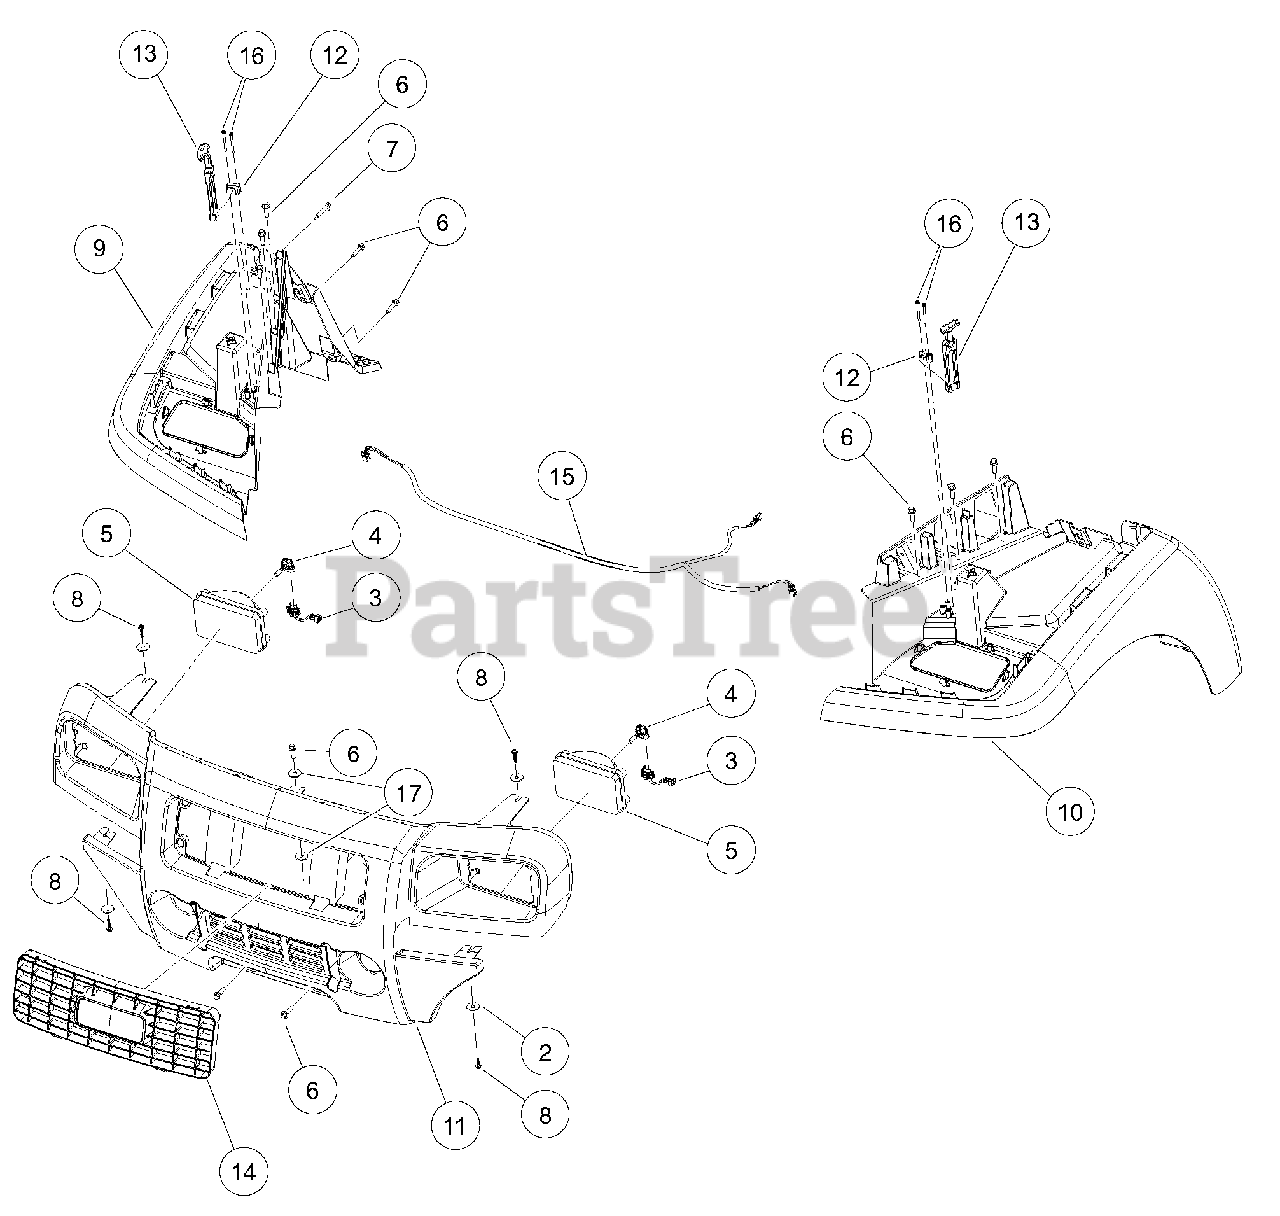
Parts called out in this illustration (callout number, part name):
1	Instl, Fascia, Fenders, CA
2	Washer, 5/16 Type B Flat
3	Connector Harness Assembly, Headlight
4	Bulb, Headlight
5	Lens, Headlight
6	Screw, M8X1.25X30, Hex
7	Screw-1/4-20x56 Hwh Self Drill
8	Screw,m6,torx,interlock,thread
9	Fender, Front, Pass, AWD
10	Fender, Front, Drv, AWD
11	Fascia, Front, CA, AWD
12	Bracket, Latch, Draw
13	Latch, Draw, Hood
14	Grill, CA295
15	Harness, XRT/CA Restyle HDL
16	Screw, #8x2.00 AB Thd, Hex Hd
17	Washer, 3/8 Type B Flat
